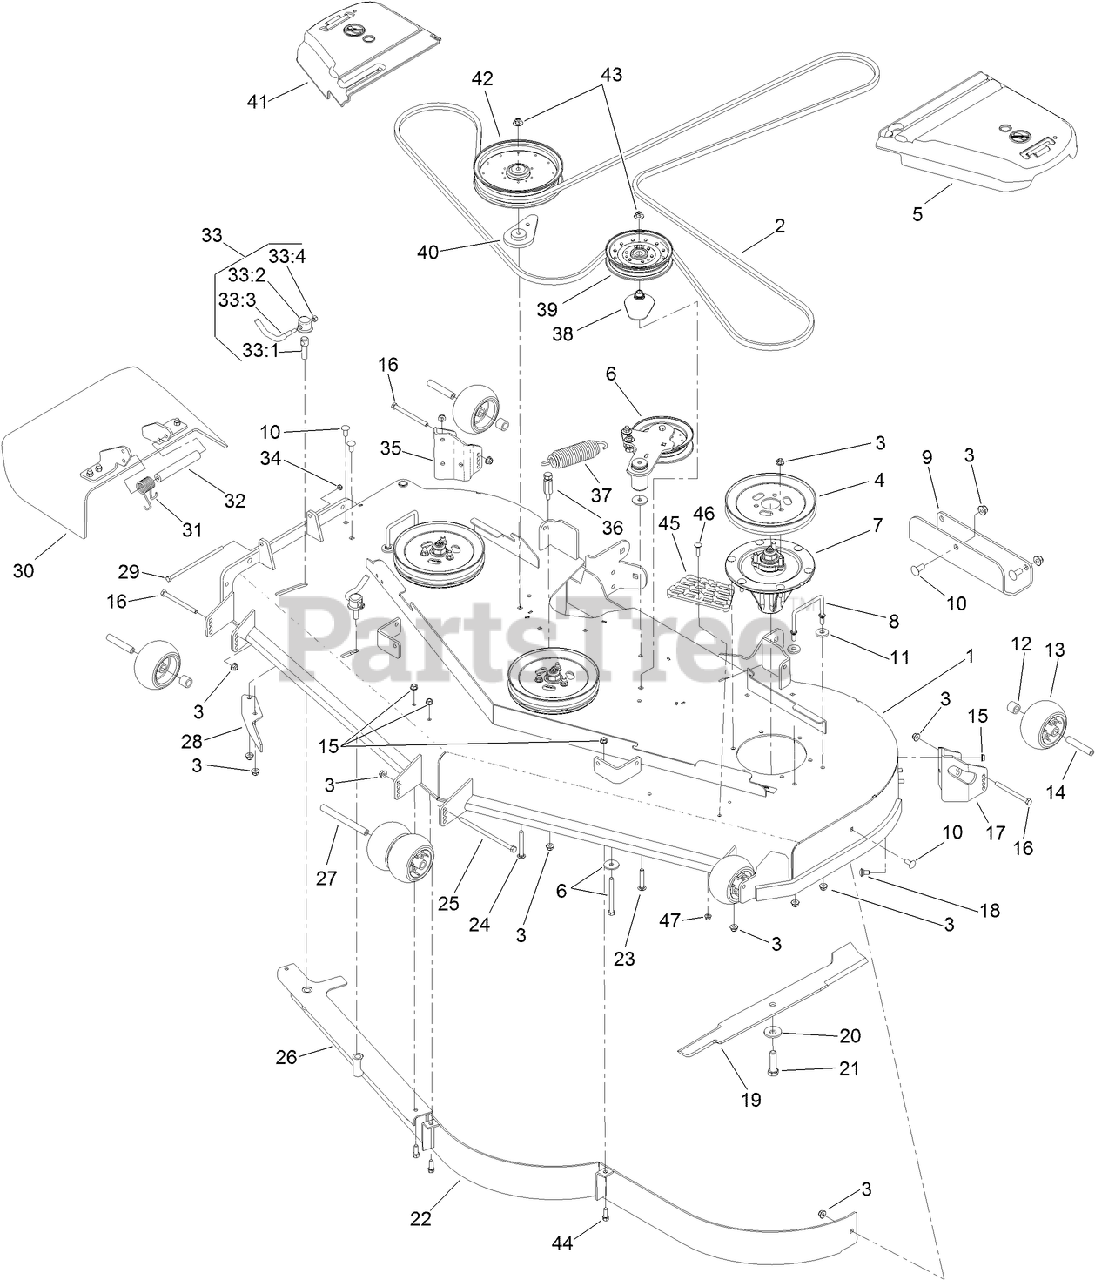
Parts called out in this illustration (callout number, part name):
1	DECK DECAL ASM
2	BELT-V
3	NUT-HF, NI
4	Pulley
5	COVER-BELT, LH
6	IDLER ARM ASM
7	SPINDLE ASM
8	WIREFORM-COVER
9	PLATE-SKID
10	SCREW-CARR
11	WASHER
12	TUBE-SPACER
13	ROLLER-SCALP, ANTI
14	TUBE-SPANNER
15	NUT-HHF, WHIZ
16	SCREW-HH
17	MOUNT-WHEEL, LH
18	SCREW-CARR
19	BLADE-HI FLOW, 24.5 INCH
20	Washer-Blade Bolt, Heavy
21	SCREW-BLADE
23	BOLT-CARR, SHORT NECK
24	SCREW-CARR
25	SCREW-HH
26	BAFFLE ASM
27	SPACER-WHEEL
28	BAFFLE-DISCHARGE
29	SCREW-HH
30	RUBBER DEFLECTOR ASM
31	SPRING-TORSION
32	SPACER
33	LEVER ASM
33:1	Screw-Lock
33:2	CAP-LOCK
33:3	Lever-Lock
33:4	NUT-LOCK, NI
34	NUT-LOCK, NI
35	MOUNT-WHEEL, RH
36	ANCHOR-SPRING, TALL
37	SPRING-EXTENSION
38	SPACER-PULLEY
39	PULLEY-IDLER, FLAT
40	SPACER-IDLER
41	COVER-BELT, RH
42	PULLEY-IDLER
43	NUT-FLANGE, NI
44	SCREW-HWH
45	STEP-DECK
46	SCREW-CARR
47	NUT-HF, NI
